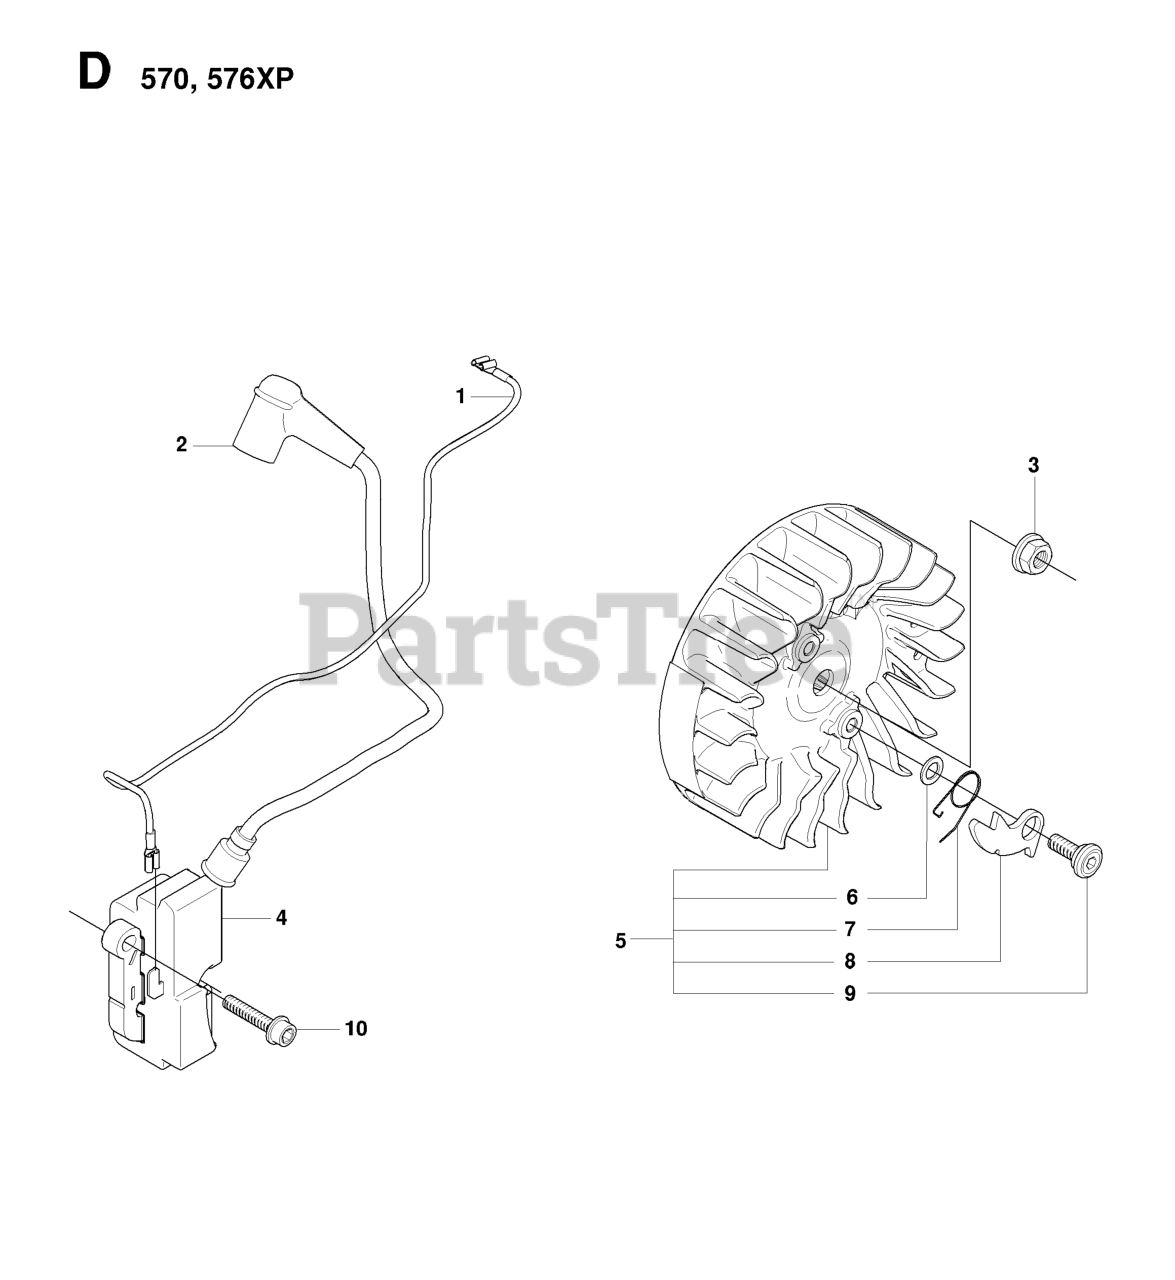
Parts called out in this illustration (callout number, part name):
1	SHORTING LEAD
2	SPARK PLUG CONN. KIT
3	NUT W/ WASHER
4	IGNITION MODULE
9	SCREW M5X14
